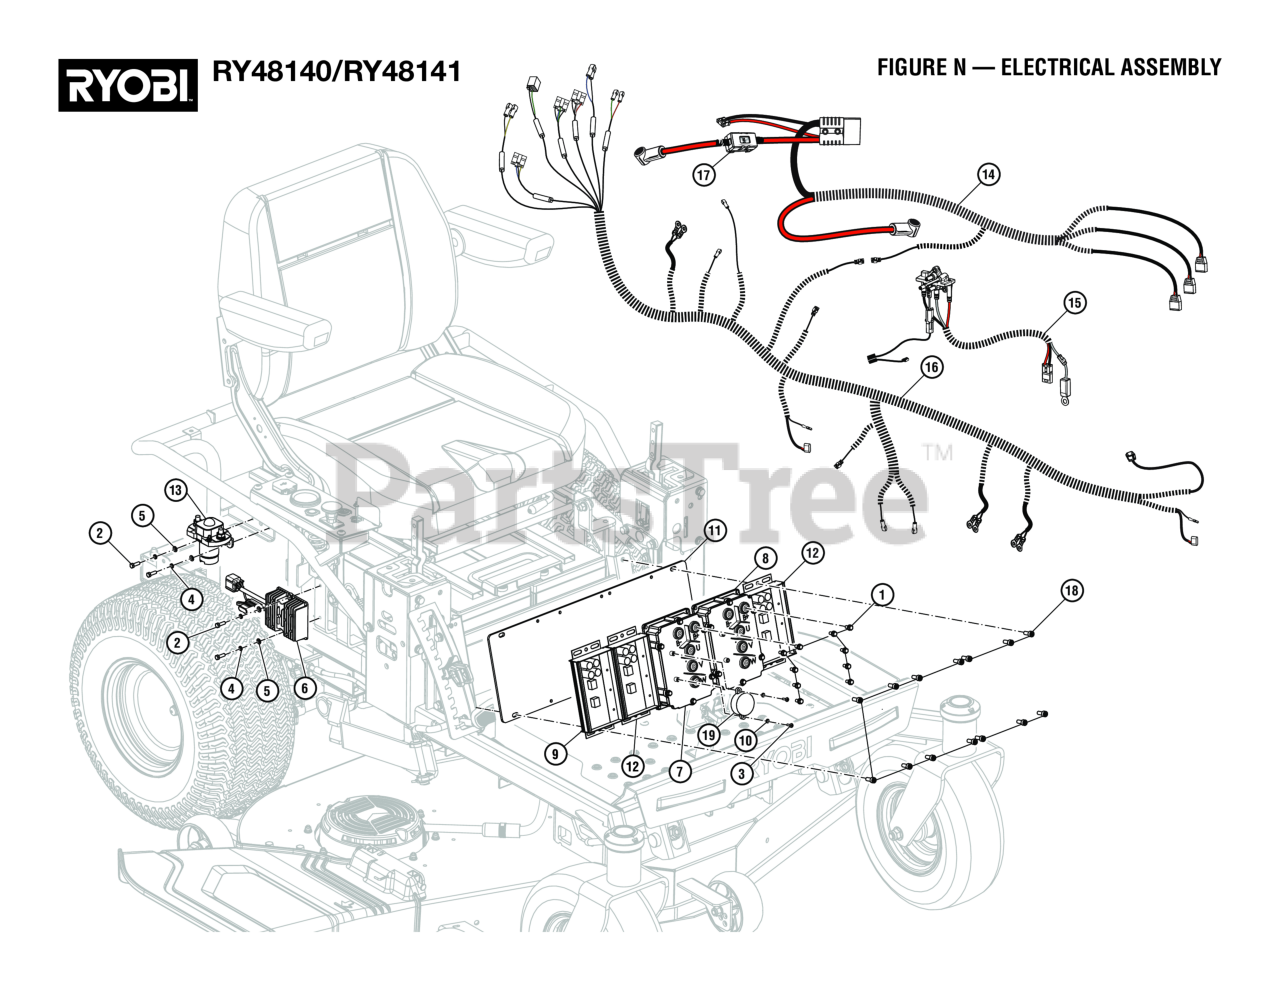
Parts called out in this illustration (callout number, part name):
1	Hex Flange Bolt (M5 x 12 mm)
2	Bolt (M5 x 16 mm, Hex hd.) (For Main Relay G)
3	Screw (M3 x 12 mm, Pan Hd.)
4	Lock Washer (For Main Relay G)
5	Washer (OD12 x ID5.3 x 1t) (For Main Relay G and Power Converter I)
6	DC to DC Converter, ZTR
7	Drive Motor Controller, Slave, ZTR
8	Drive Motor Controller, Master, ZTR
9	Deck Motor Controller, Master
10	Washer (OD7 x ID3.2 x 0.6t) (For Beeper Q)
11	Controller Mounting Plate
12	Deck Motor Controller, Slave
13	Main Relay (G)
14	Battery Output Cable.
15	Charging Controller, ZTR
16	Main Wiring Harness
17	Fuse, 125 Amp
18	Screw (M6 x 16 mm, Soc. Hd.)
19	Beeper, ZTR
